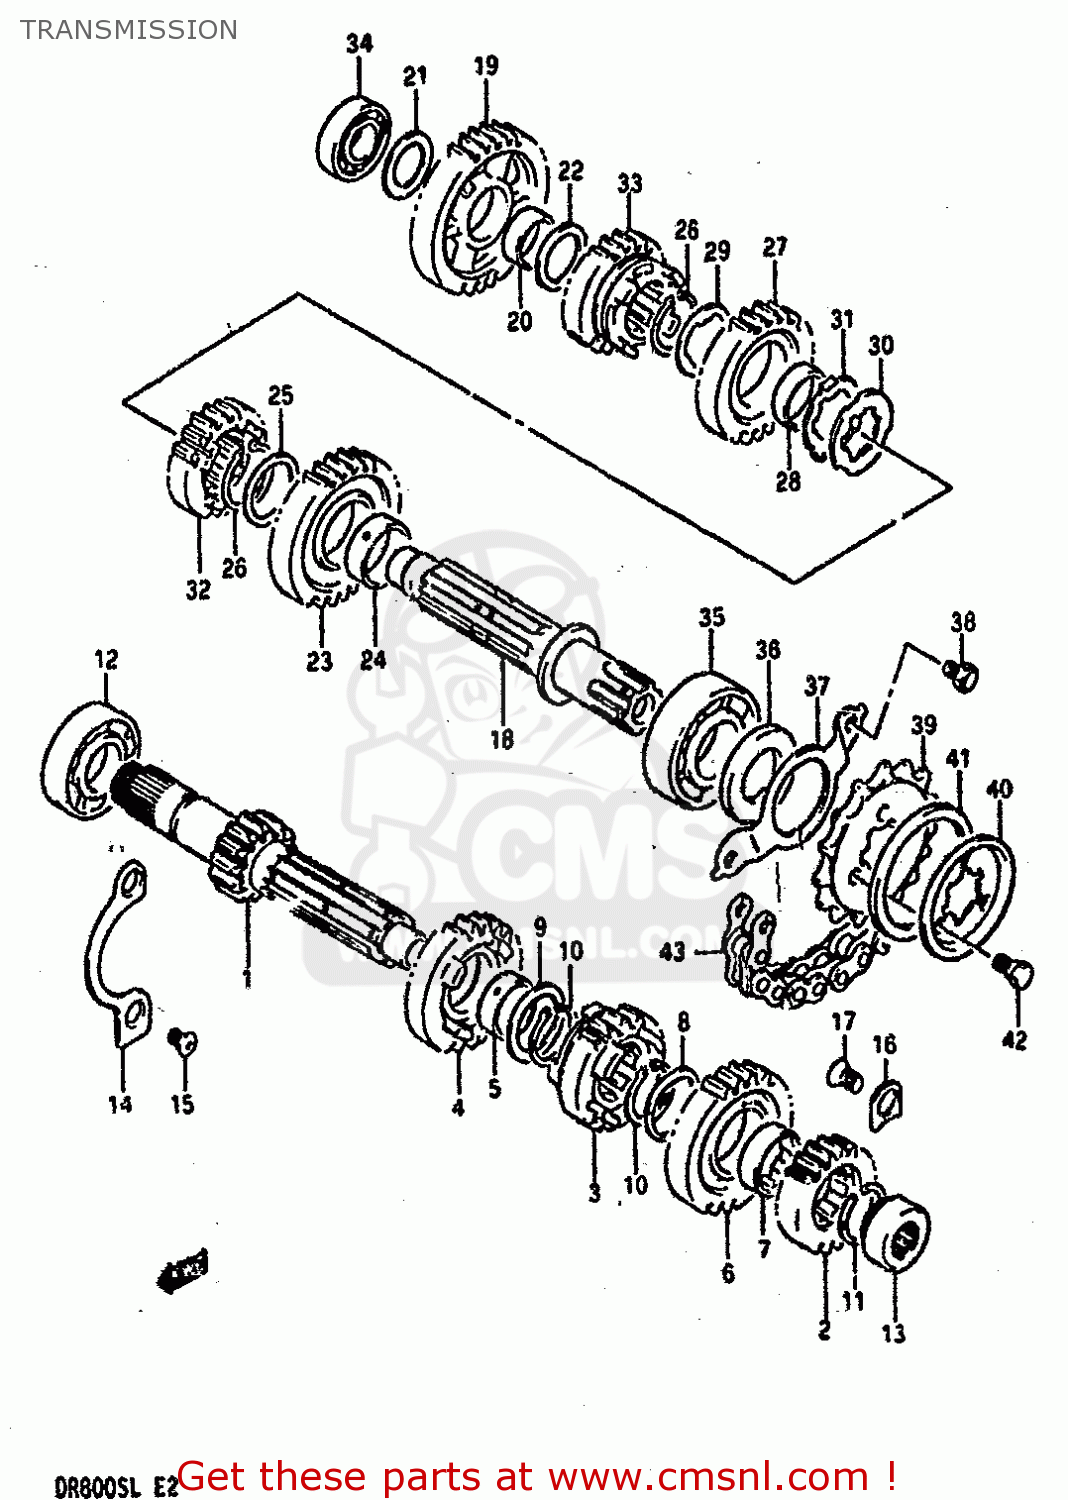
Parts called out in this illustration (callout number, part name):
1	COUNTERSHAFT (NT:13)
2	GEAR,2ND DRIVE (NT:19)
3	GEAR,THIRD DRIVE (NT:20)
4	GEAR,4TH DRIVE(NT:23)
5	BUSHING 25X29X10
6	GEAR,FIFTH DRIVE (NT:25)
7	BUSHING
8	WASHER,LOCK
9	WASHER
10	RING,SNAP
11	CIRCLIP
12	BEARING
13	BEARING(17X30X14)
14	RETAINER,CNTR SHAFT BEARING
15	SCREW
16	RETAINER
17	SCREW
18	SHAFT,DRIVE
19	GEAR,1ST DRIVEN (NT:32)
20	BUSHING
21	WASHER,THRUST
22	WASHER
23	GEAR,2ND DRIVEN (NT:30)
24	BUSH(28X32X11)
25	WASHER
26	CIRCLIP
27	GEAR,THIRD DRIVEN (NT:24)
28	BUSH
29	WASHER,LOCK
30	WASHER,LOCK
31	WASHER
32	GEAR,FOURTH DRIVEN (NT:22)
33	GEAR,FIFTH DRIVEN (NT:20)
34	BEARING(20X42X12)
35	BEARING(25X62X17)
36	SEAL,OIL(25X45X5)
37	RETAINER,DRIVESHAFT O
38	BOLT
39	SPROCKET,ENGINE(15T)
40	PLATE,ENGINE SPROCKET
41	DAMPER,ENGINE SPROCKET
42	BOLT(6X13)
43	CHAIN(DID520VL2,116L)
